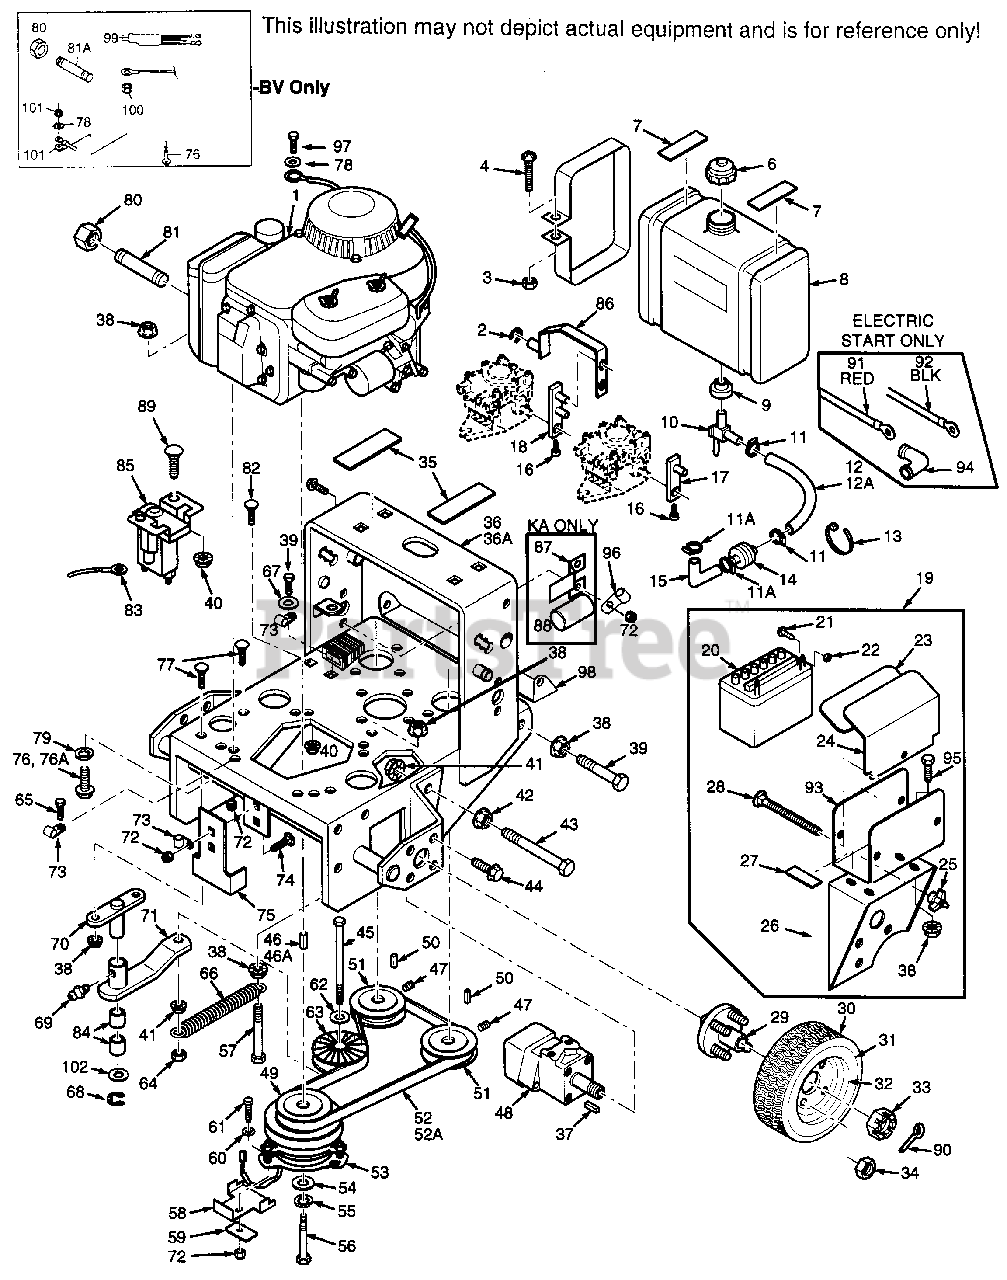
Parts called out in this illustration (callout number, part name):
2	RETAINING RING, 1/2" EXT. "E"
4	SCREW, 1/4-20 X 2" RND. HD. PHIL.
5	STRAP, FUEL TANK
6	CAP, FUEL TANK
7	PAD, RUBBER-FUEL TANK - UPPER
8	FUEL TANK ASSY.(INCL. 9, 10)
9	BUSHING
10	VALVE, FUEL SHUT-OFF
11	CLAMP, FUEL HOSE
13	CABLE TIE
16	CAPSCREW, #10-32 X 1 SOC. HD.
17	LEVER ASSY., PUMP CONTROL -LH
18	LEVER ASSY., PUMP CONTROL -RH
29	HUB, WHEEL(INCL. 34)
30	WHEEL ASSY.,(INCL. 29,31,32,34)
31	TIRE, 16 X 6.50, 4 PLY
32	RIM ASSY
33	HEX CASTLE NUT, 3/4-28 UNEF
34	NUT, LUG
35	PAD, RUBBER-FUEL TANK, LOWER
36A	ENGINE DECK, 20" WIDE, W/DECLS.
37	KEY, 3/16 X 3/16 X .75
38	NUT, 5/16-18 SERR. FLANGE
39	BOLT, 5/16-18 X 1-1/2" HEX HEAD
40	NUT, 1/4-20 SERRATED FLANGE
41	NUT, 3/8-16 SERR. FLANGE
42	CAPSCR., 5/16-18 X 1.25 SR. FLG.
43	BOLT, 3/8-16 X 2-3/4" HEX HEAD
44	CAPSCREW, 3/8-16 X 1" SERR. FLG.
47	SETSCREW, 5/16-18 X 3/8"
48	WHEEL MOTOR
49	PULLEY, PUMP DRIVE ENGINE
50	KEY, 5.0 X 5.0 X 25MM
51	PULLEY, PUMP SHAFT
52A	BELT, PUMP DRIVE
53	ELECTRIC CLUTCH
54	FLAT WASHER, 7/16
57	HEX HEAD BOLT, 5/16-18 X 2.75"
58	BACKING PLATE, CLUTCH STOP
59	RUBBER PAD, CLUTCH STOP
62	FLAT WASHER, 3/8
63	PULLEY, IDLER PUMP DRIVE
64	NUT, 3/8-16 CENTER LOCK
65	HEX HEAD BOLT, 5/16-18 X .75"
66	SPRING, PUMP BELT IDLER
67	FLAT WASHER, 1/4
68	RETAINING RING, 3/4 EXT. "E"
69	GREASE FITTING, STR. 1/4-28
70	PIVOT, IDLER ARM
71	IDLER ARM,(INCL. 69 & 84)
72	NUT, 5/16-18 ELASTIC STOP
74	CARRAGE BOLT, 5/16-18 X 1"
75	CLUTCH BRACKET
78	LOCK WASHER, 5/16 INT. TOOTH
84	BUSHING, 3/4 SINTERED
86	SHAFT WELDMENT, RH PUMP CNTL.
90	COTTER PIN, 3/32 X 1.25"
96	CABLE CLAMP, .75 ID
98	PULLEY GUARD, 20" FRAME
100	NUT, 1/4-20 ELASTIC STOP
102	WASHER, 3/4-.766 X 1.2 X .06
102	WASHER, 3/4-.766 X 1.2 X .035
